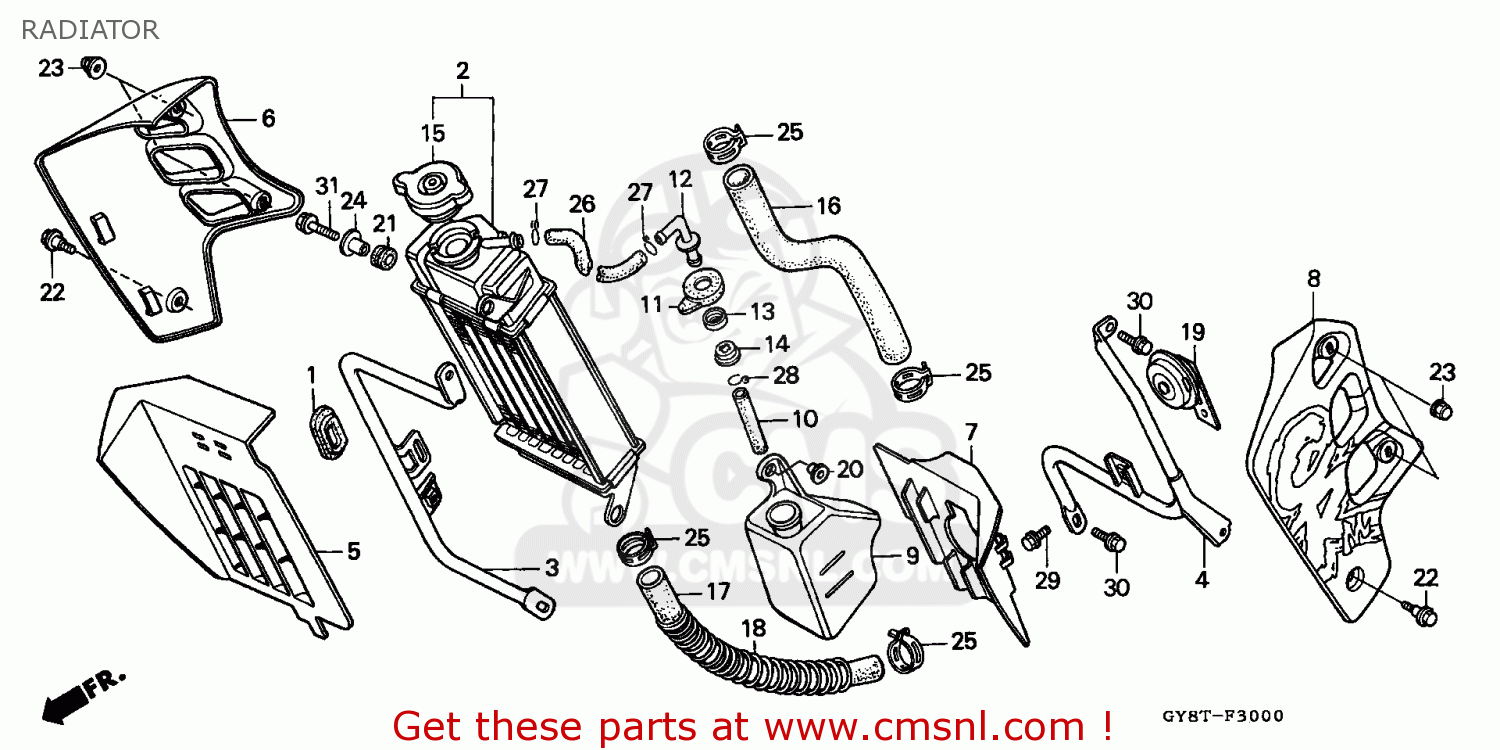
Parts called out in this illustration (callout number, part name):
1	GROMMET
2	RADIATOR ASSY
3	STAY R. GRILL
4	STAY L. GRILL
5	GRILL R. RADIATOR
6	SHROUD SET, R. (WL)
7	GRILL L. RADIATOR
8	SHROUD SET, L. (WL)
9	TANK,RESERVE
10	HOSE,RESERVE TANK
11	CAP,RESERVE TANK
12	ADAPT,RESERVE CAP
13	STOP,RAD.FLUID
14	STOPPER A RAD FLU
15	CAP RADIATOR
16	HOSE A,WATER
17	HOSE B,WATER
18	WIRE GUARD
19	HORN COMP.(HIGH)
20	COLLAR,FEND.SET.
21	GROMMET,A LEG
22	BOLT,SHROUD SETTI
23	NUT,CAP,6MM
24	COLLAR,BRKT,MT
25	CLAMP CNSTR HOSE
26	TUBE,FUEL,7.3X190
27	CLIP B12,TUBE
28	CLIP C11,TUBE
29	BOLT.FLANG 6X10
30	BOLT,FLANGE,DR,6X
31	BOLT,FLANGE,6X22
